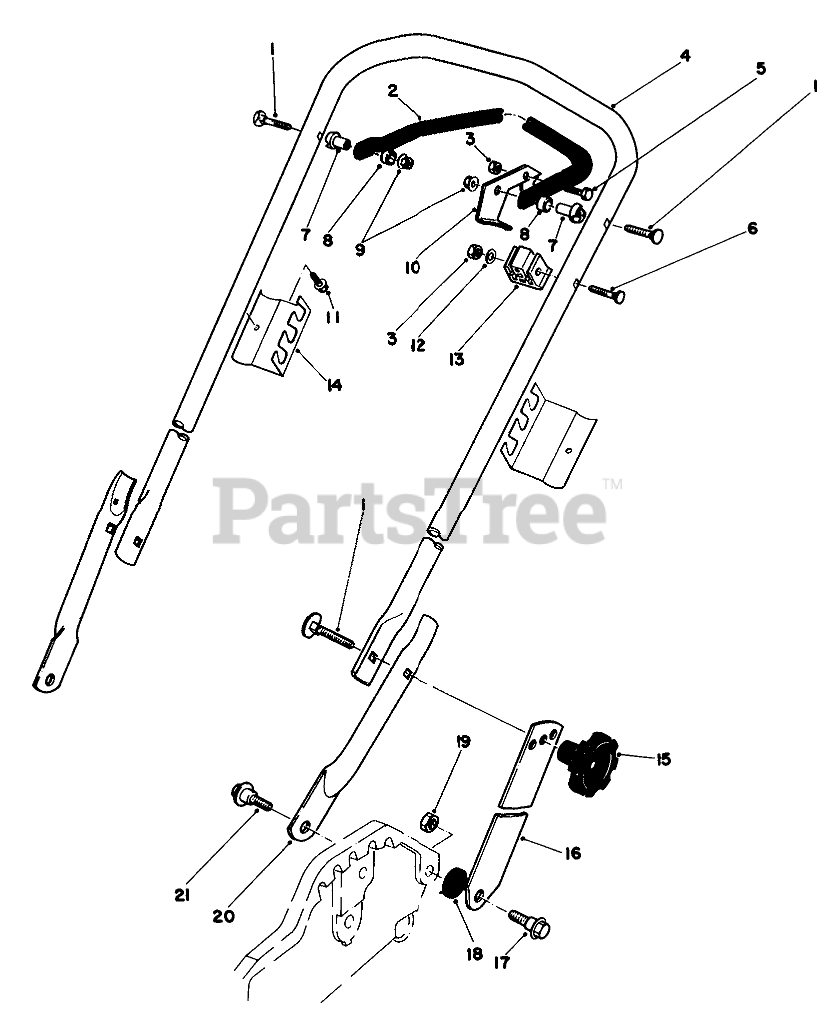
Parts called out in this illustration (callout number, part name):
1	5/16-18 X 2 HNDLE SCREW
2	CONTROL BAR
3	NUT-LOCK, NI
4	Handle-Upper
5	SCREW-HH
6	SCREW-HANDLE
7	SPACER-SUPPORT
8	SPACER-NYLON
9	NUT-LOCK, NI
10	Lever-Control
11	SCREW-HWHTF
12	WASHER-FLAT
13	SUPPORT-CABLE
14	Bag Support
16	Handle Latch
17	SCREW-SHOULDER
18	SPACER
19	NUT-LOCK, NI
20	Hand-Lower
21	SCREW-SHOULDER
